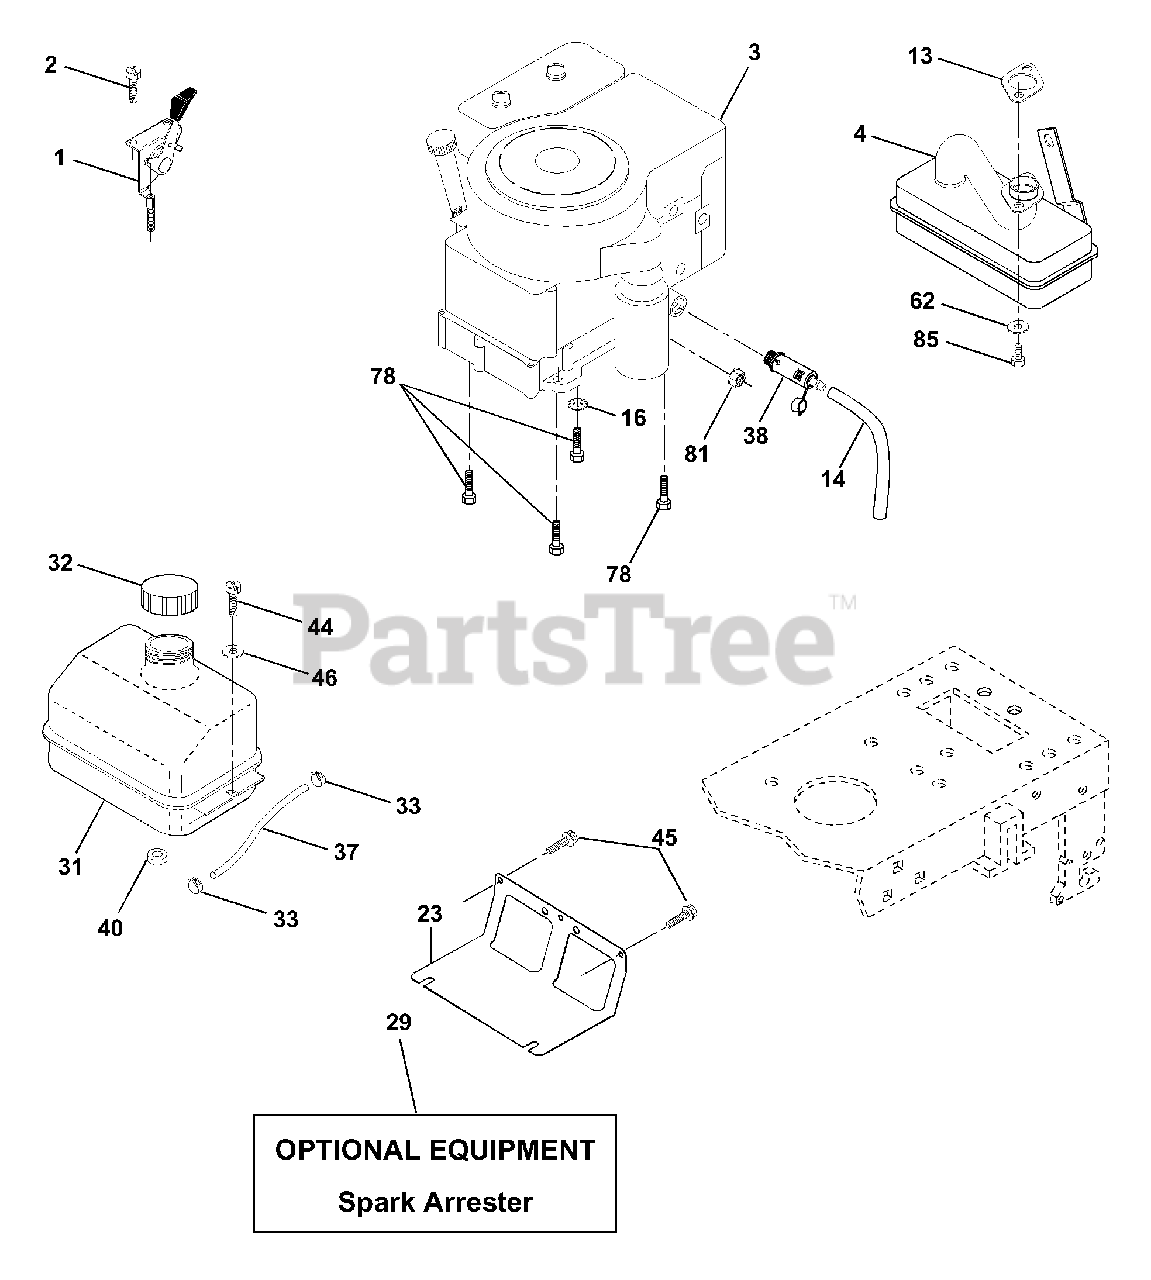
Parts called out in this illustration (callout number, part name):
1	Control Th/ch LH Flag
2	Screw Hex Thd Cut 1/4-20x5/8 T
4	Muffler
13	Gasket Eng 1 313 Id Tin Plated
14	Tube Drain Oil Easy
16	Washer Lock Ext Tooth 3/8
23	Shield Browning/Debris Guard
29	Kit Spark Arrestor (Flat Scrn)
31	Tank Fuel Front 1 25
32	Cap Asm Fuel Top Vented
33	Clamp Hose Blk
37	Line Fuel 20"
38	Plug Oil Drain
40	Bushing Snap Nyl Blk Fuel Line
44	Screw Hexwsh Thdrol 1/4-20 x 3/4
45	Screw 3/8-16 x 3/4
46	Washer 9/32 x 7/8 x 16 ga
62	Washer Lock Hvy Hlcl Spr 5/16
78	Screw 3/8-16 x 1-1/4
81	Nut Keps Hex 1/4-20 UNC
85	Bolt Hex
